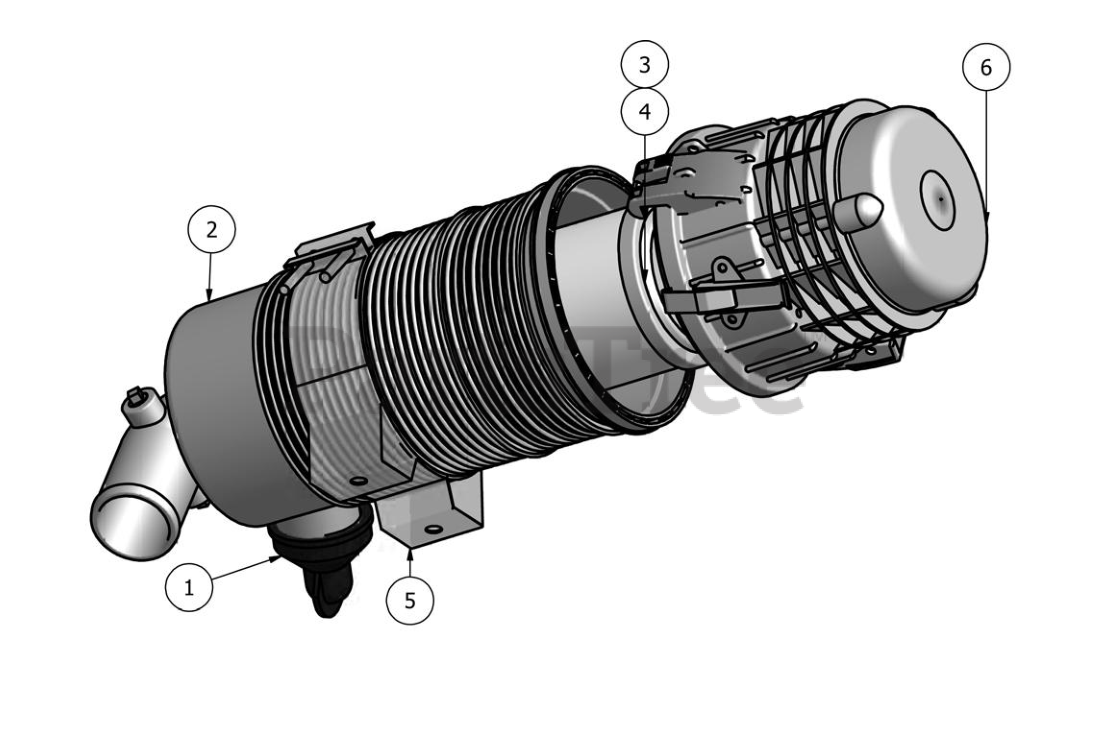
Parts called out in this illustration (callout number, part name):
1	Debris Plug
2	Canister Body
3	Inner Filter
4	Outer Filter
5	Mounting Bracket
6	Filter Cap
7	Complete Unit
